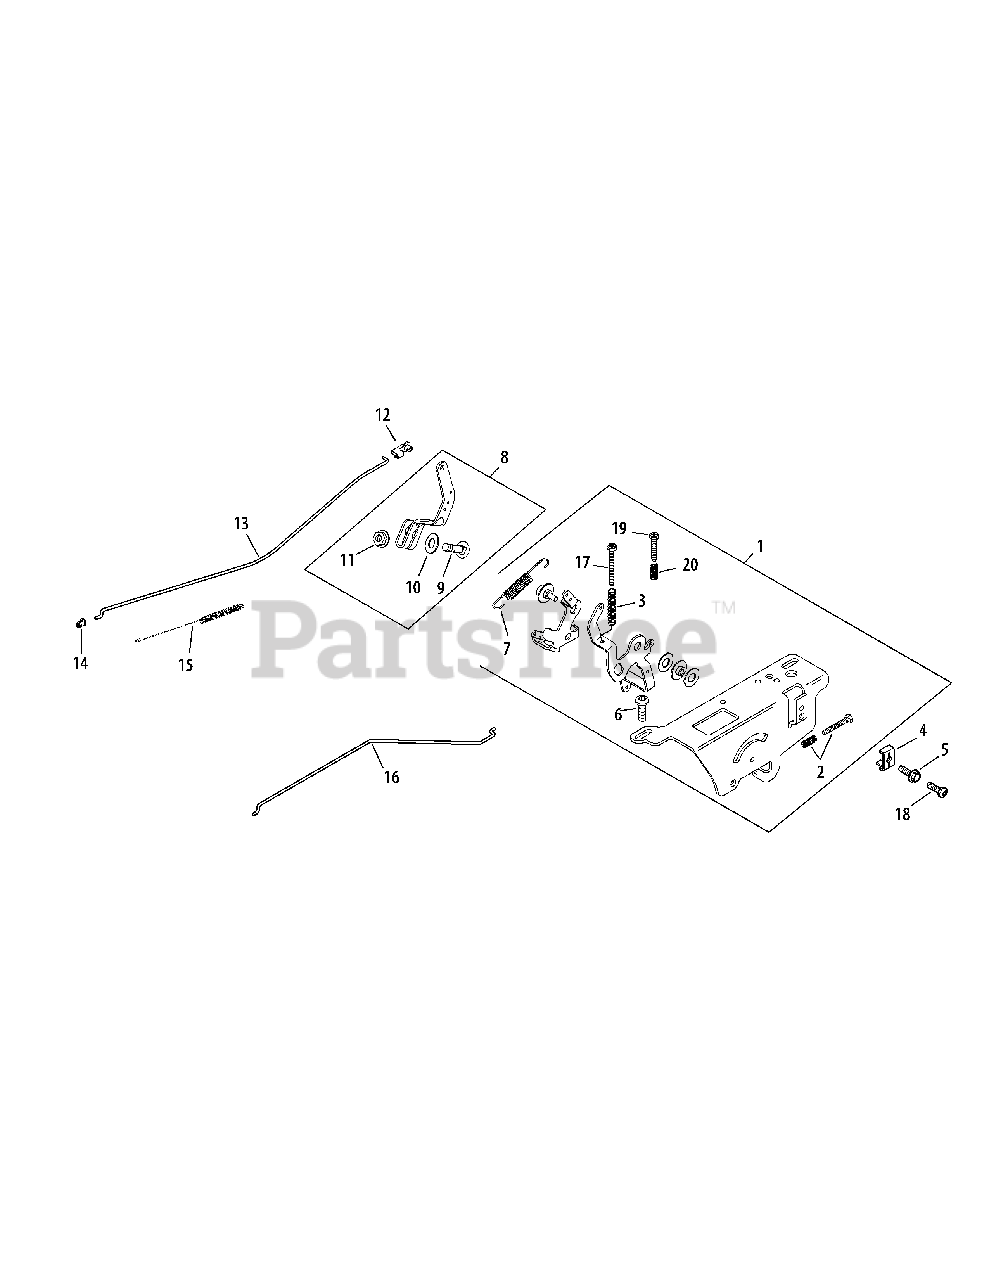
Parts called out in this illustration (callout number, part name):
1	Speed Control Assembly Kit (Inc. 2, 3, 6, 7, 17, 19, 20)
2	Idle Adj. Screw & Spring Kit
3	Speed Control Spring (Long)
4	Cable Clamp
5	Flg. Thd. Frm. Screw, M5 X 0.8 X 16
6	Lbd. Skt. Screw, M6 X 1.0 X 20
7	Governor Spring
8	Governor Ass’y Lever (Inc. 9-11)
9	Rd. Hd. Sq. Nck. Bolt, 1/4-20 X 1
10	Int. Tooth Lock Washer, 1/4
11	Hex Flg Nut, 1/4-20
12	Throttle Linkage Bushing
13	Throttle Linkage
14	Linkage Retaining Bushing
15	Linkage Spring
16	Choke Linkage
17	Screw, Choke Adj M4 x 0.7 x 38
19	Phl. Thd. Frm. Screw, M4 X 0.7 X 25
20	Speed Control Spring (Short)
